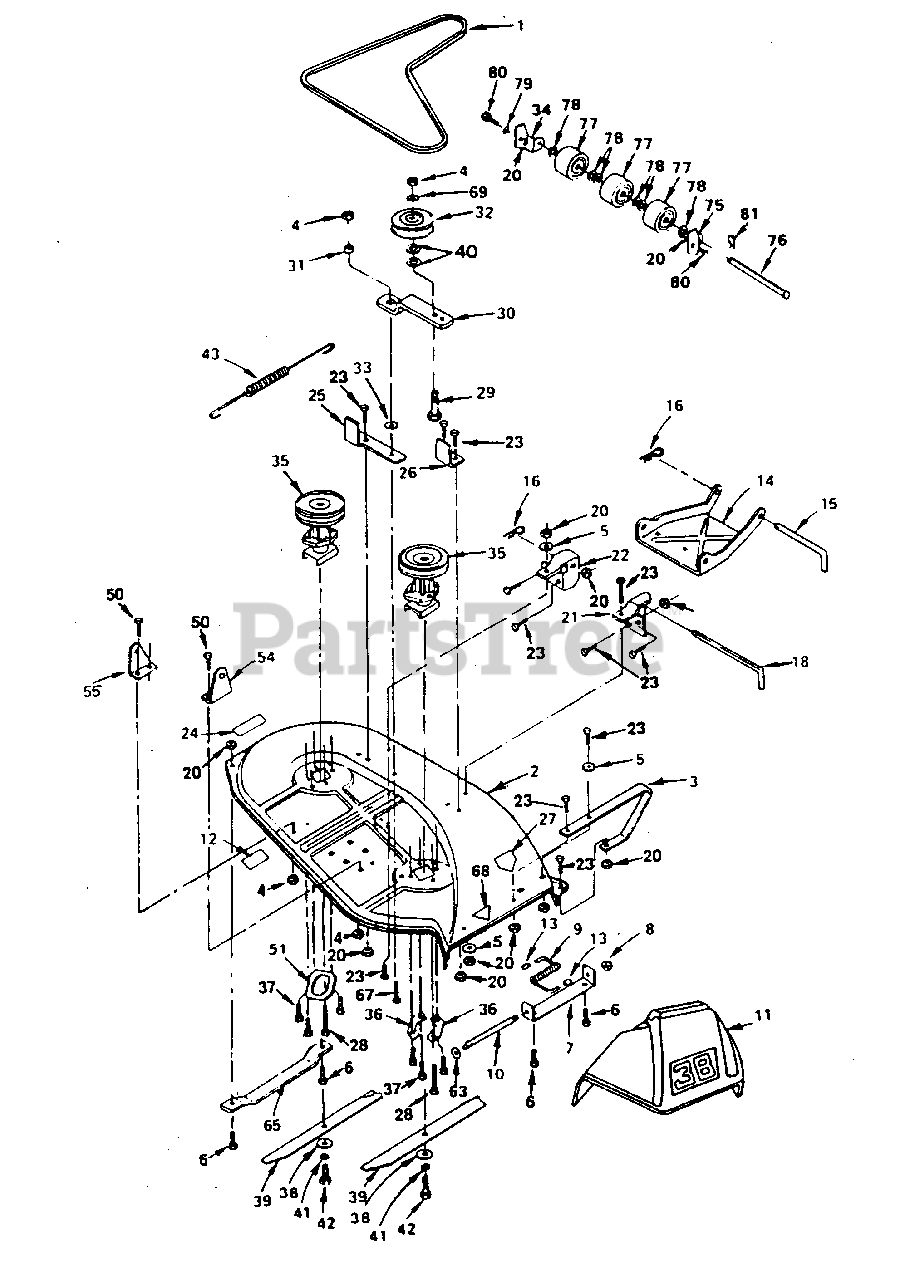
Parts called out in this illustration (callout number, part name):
1	V-Belt (AYP part number)
2	Housing (AYP part number)
3	R.H. Runner (AYP part number)
4	Locknut
5	Washer (AYP part number)
6	Carriage Bolt (AYP part number)
7	Deflector Bolt (AYP part number)
8	Push Nut (AYP part number)
9	Deflector Spring (AYP part number)
10	Hinge Rod (AYP part number)
11	Shield Deflector (AYP part number)
12	V-Belt Schematic Decal (AYP part number)
13	Sleeve Cap (AYP part number)
14	Paralle Link (AYP part number)
15	Front Hinge Pin (AYP part number)
16	Retainer Spring (AYP part number)
18	Rear Hinge Pin (AYP part number)
20	Locknut (AYP part number)
21	R.H. Lift Bracket (AYP part number)
22	L.H. Lift Bracket (AYP part number)
23	Carriage Bolt 5/16-18 x 3/4
24	Caution Instruction Decal (AYP part number)
25	Arm Support (AYP part number)
26	Front Deck Stop (AYP part number)
29	Bolt 3/8-16 x 2 (AYP part number)
30	Idler Arm (AYP part number)
31	Spacer (AYP part number)
32	Idler Pulley (AYP part number)
33	Wear Washer (AYP part number)
34	L.H. Nose Roller Bracket (AYP part number)
35	Mandrel Assembly (AYP part number)
36	Mandrel Support Plate (AYP part number)
37	Washer Hd. Hex Screw (AYP part number)
38	Washer Hd. Hex Screw (AYP part number)
39	Blade 38"
40	Washer (AYP part number)
41	Washer (AYP part number)
42	Hex Bolt 3/8-24 x 1-1/2 Gr. 5 (AYP part number)
43	Extension Spring (AYP part number)
44	Washer (AYP part number)
50	Carriage Bolt 3/8-16 x 3/4 (AYP part number)
51	Support Plate (AYP part number)
54	R.H. Rear Bracket Suspension (AYP part number)
55	L.H. Rear Bracket Suspension (AYP part number)
63	Washer (AYP part number)
65	L.H. Runner (AYP part number)
67	Carriage Bolt (AYP part number)
68	Warning Decal (AYP part number)
69	Washer (AYP part number)
75	R.H. Nose Roller Bracket
76	Pivot Pin (AYP part number)
77	Nose Roller (AYP part number)
78	Washer (AYP part number)
79	Washer (AYP part number)
80	Hex Bolt (AYP part number)
81	Cotter Pin (AYP part number)
